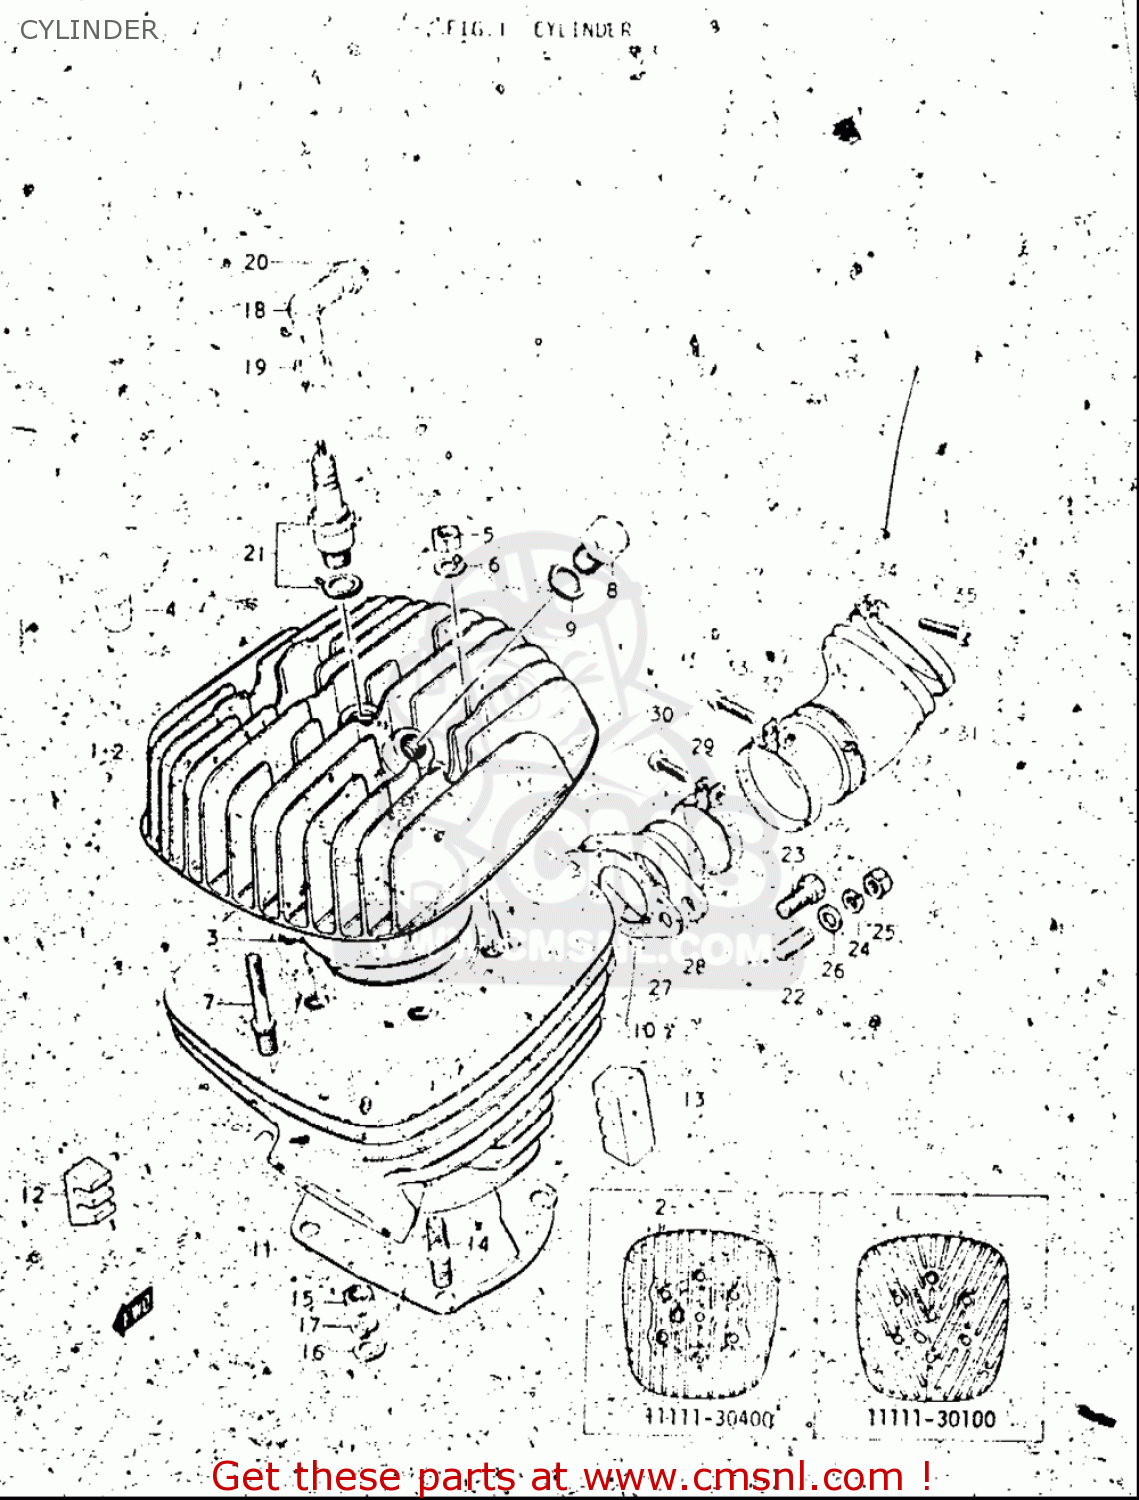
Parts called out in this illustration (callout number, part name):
3	GASKET,CYLINDER HEAD (NAS)
4	PAD,CYLINDER
5	NUT
6	WASHER
7	BOLT,STUD
8	PLUG
9	GASKET(14X19.2X2) (NAS)
11	GASKET,CYLINDER
14	STUD 10X30
15	NUT
16	WASHER
17	WASHER,LOCK
18	CAP ASSEMBLY,SPARK PLUG
19	SEAL,SPARK PLUG
21	PLUG,SPARK
22	STUD BOLT
23	BOLT
24	WASHER,LOCK
25	NUT
26	WASHER
27	GASKET,CARBURETOR (NAS)
28	PIPE,INTAKE
29	CLAMP
30	SCREW
33	SCREW
34	CLAMP
35	SCREW
